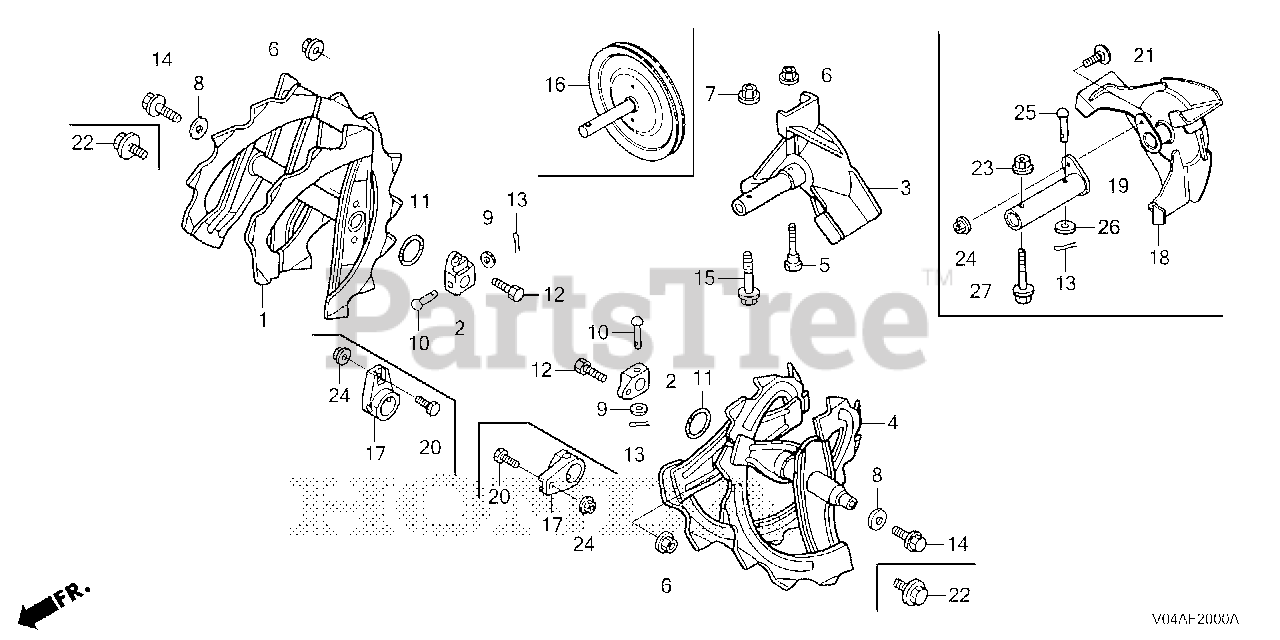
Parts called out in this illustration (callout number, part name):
2	BOSS, LOCK BOLT
5	BOLT, LOCK
6	NUT, SELF-LOCK (6MM)
7	NUT, FLANGE (M8X1.25) (SELF-LOCK)
8	WASHER (23X8.3X3.2)
9	WASHER, PLAIN (7MM)
10	PIN (7X40)
11	O-RING (19.8X1.9) (ARAI)
12	BOLT, HEX. (6X16)
13	PIN, SPLIT (3.0X25)
13	PIN, SPLIT (3.0X45)
14	BOLT, FLANGE (8X16)
15	BOLT, FLANGE (8X35)
